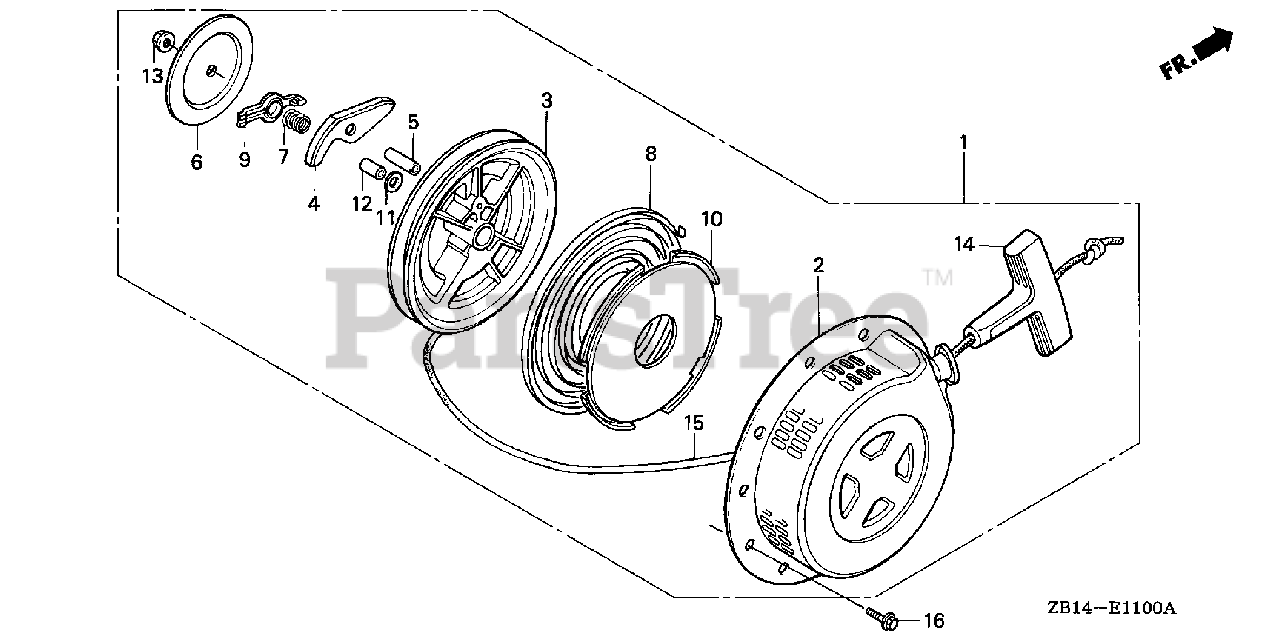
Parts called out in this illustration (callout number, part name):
1	STARTER ASSY., RECOIL *R8* (BRIGHT RED)
1	STARTER ASSY., RECOIL *R280* (POWER RED)
2	CASE, RECOIL STARTER *R8* (BRIGHT RED)
3	PULLEY, RECOIL STARTER
4	RATCHET, STARTER
5	PIN, STARTER RATCHET
6	PLATE, FRICTION
7	SPRING, FRICTION
8	SPRING, RECOIL STARTER
9	GUIDE, RATCHET
10	CASE, RECOIL STARTER SPRING
11	WASHER, STARTER
12	SHAFT, SUB
14	KNOB, RECOIL STARTER
15	ROPE, RECOIL STARTER
16	BOLT, FLANGE (6X8)
